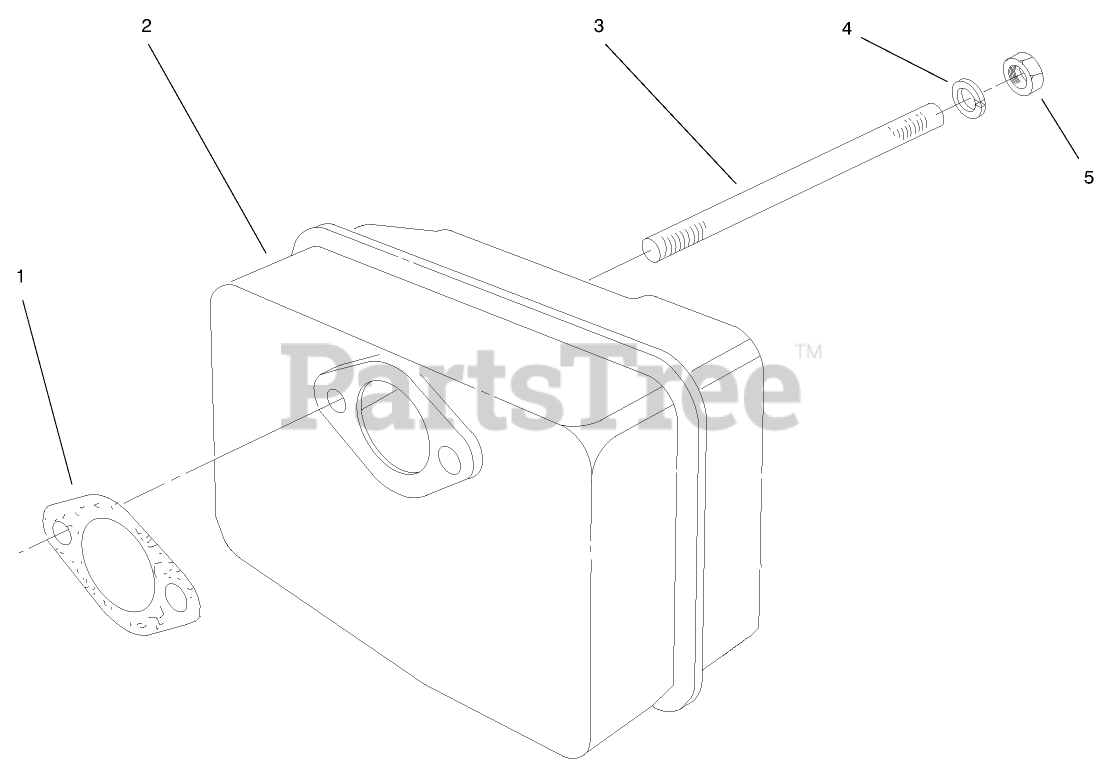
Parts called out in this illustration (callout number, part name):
1	GASKET
2	MUFFLER
4	WASHER-LOCK
